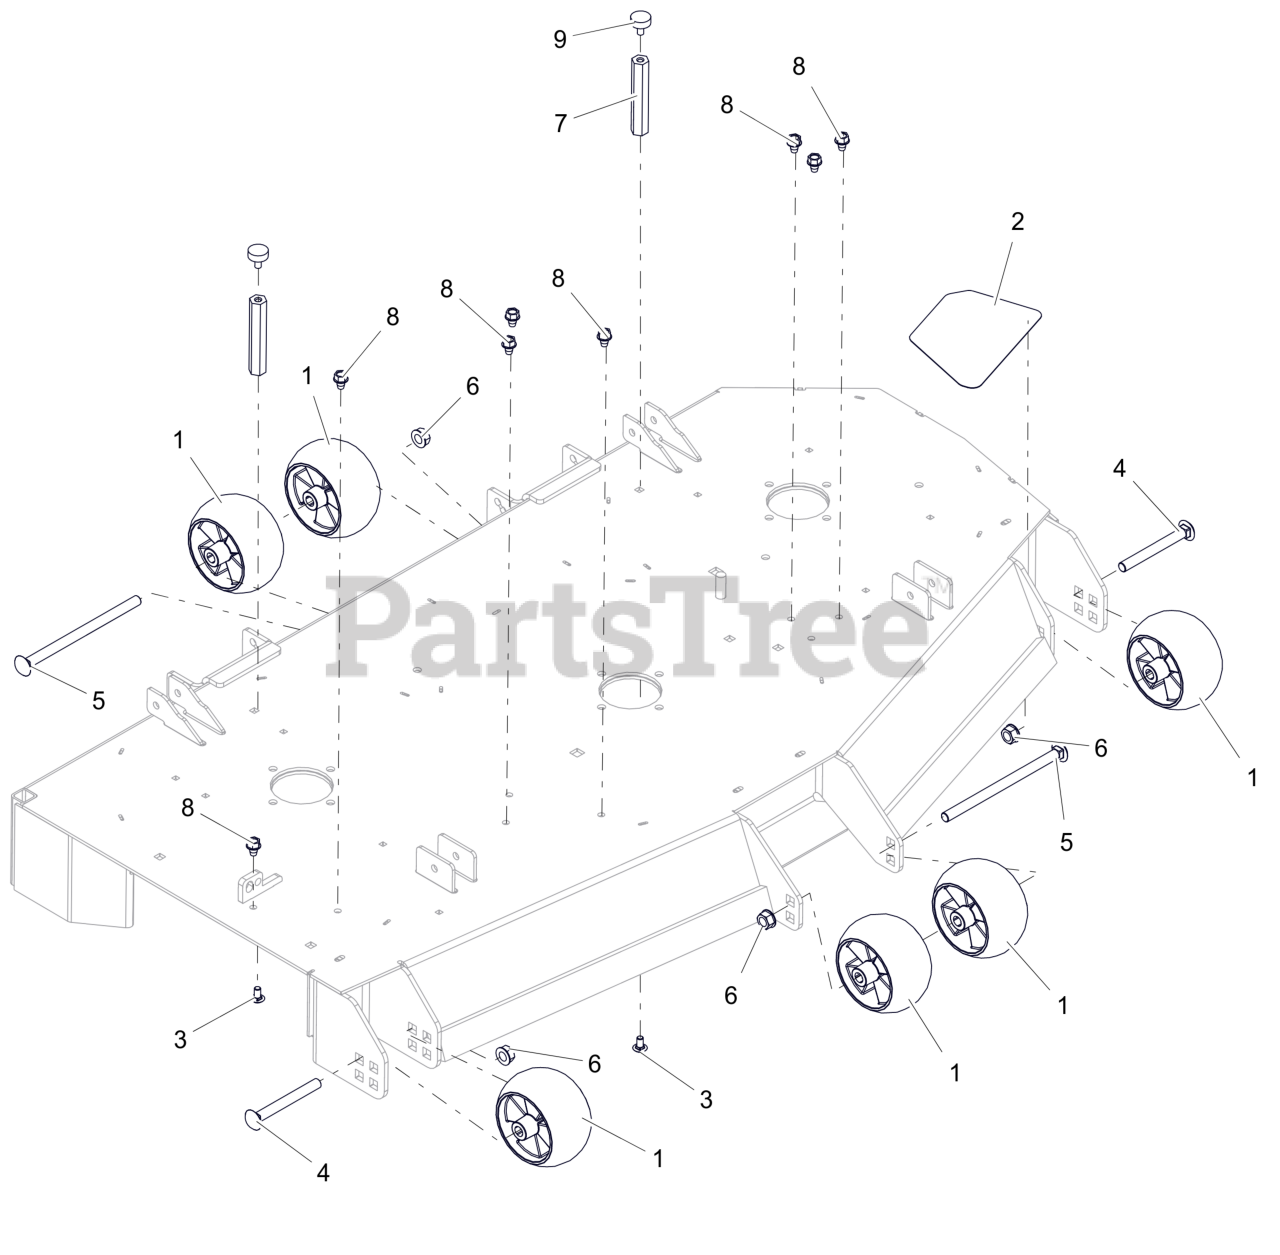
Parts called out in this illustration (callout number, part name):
1	WHEEL, ANTI SCALP - 5X3 CTR W/RIBS
2	GRIP, STEP ANTI SKID
3	BTL,RHSSN .313-18 X 0.625 G5 ZCC
4	BLT,RHSN .50-13X4.50 G5 ZCC
5	BTL,RHSN .500-13 X 8 G5 ZCC
6	NUT-LK-CTR-FLG .500-13 GG ZCC
7	NUT, COUPLING .312-18 X 4.295
8	SCR,TAP .375-16X.50 HWH TR ZCC
9	BUMPER, RUBBER
